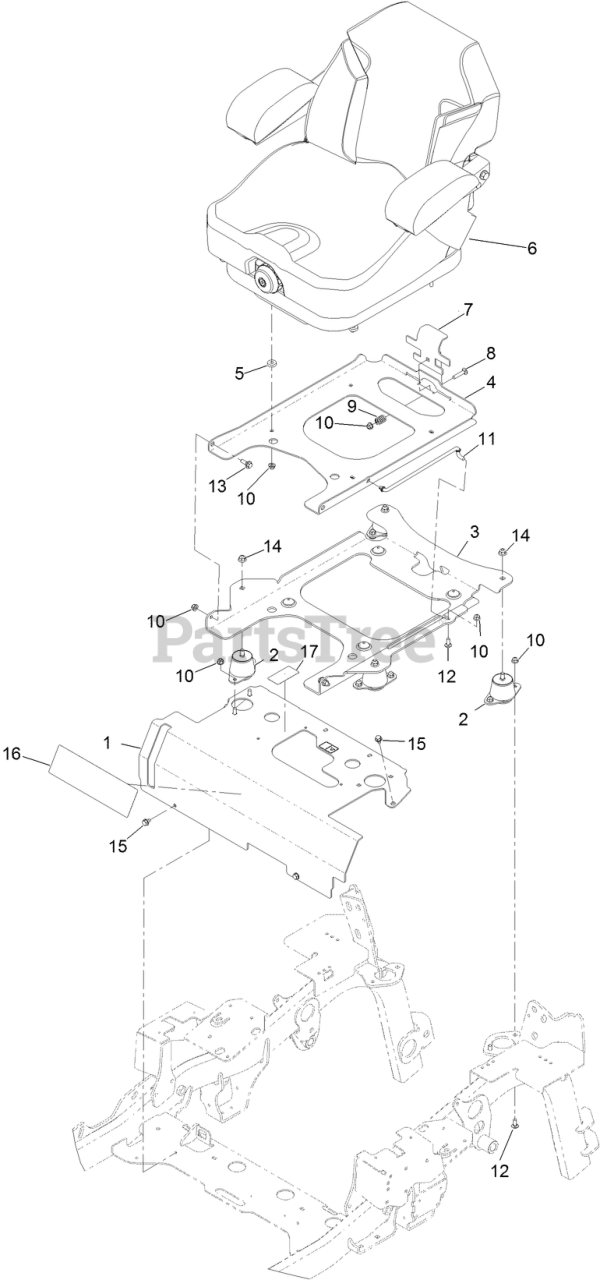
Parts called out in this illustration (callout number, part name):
1	SEAT MOUNT ASM
2	ISOLATOR-SEAT
3	PLATE-SUPPORT, TILT SEAT
4	PLATE-FRAME, SEAT
6	SEAT-SUSPENSION
7	PLATE, SEAT LATCH
8	BOLT-CARR
9	SPRING-COMPRESSION
10	NUT-HF, NI
11	ROD-PROP
12	SCREW-CARR
13	SCREW-SHOULDER
14	NUT-HF, NI
15	SCREW
16	DECAL-CONSOLE
17	DECAL-FLUID, TRANSMISSION
